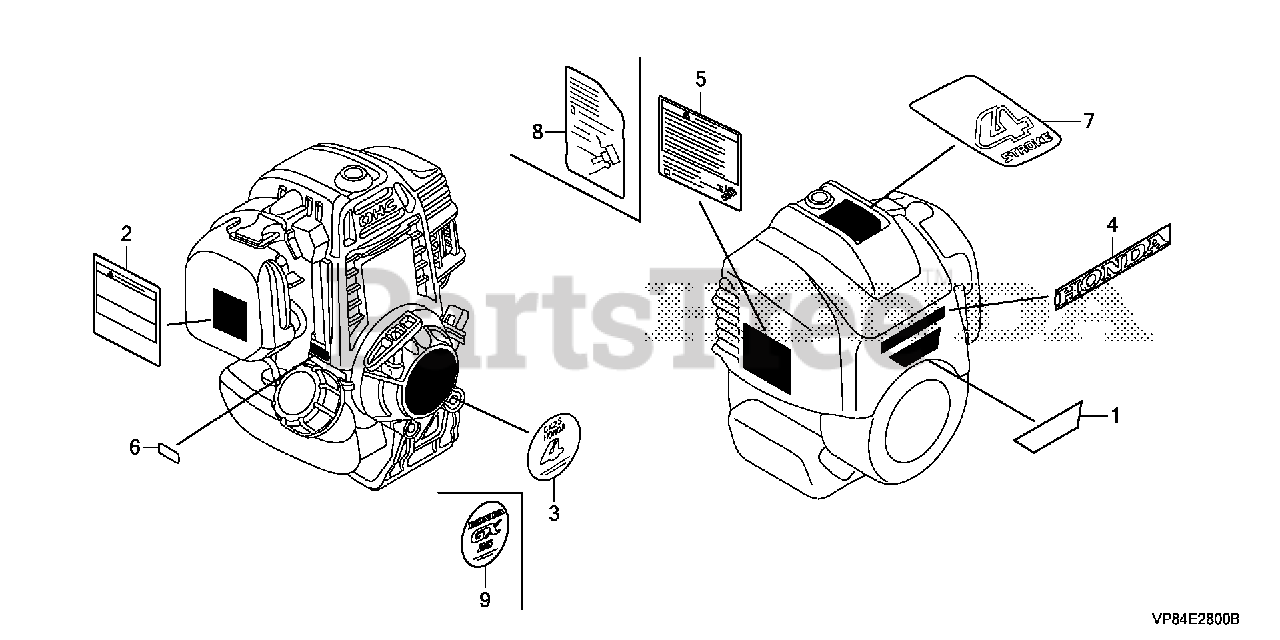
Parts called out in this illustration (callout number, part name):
1	MARK, EMBLEM (UMC425)
2	MARK, OPERATOR CAUTION (ENGLISH)
3	MARK, EMBLEM
4	MARK, HONDA
5	LABEL, SPARK WARNING
6	MARK, TYPE
7	MARK (4-STROKE)
9	MARK, EMBLEM
